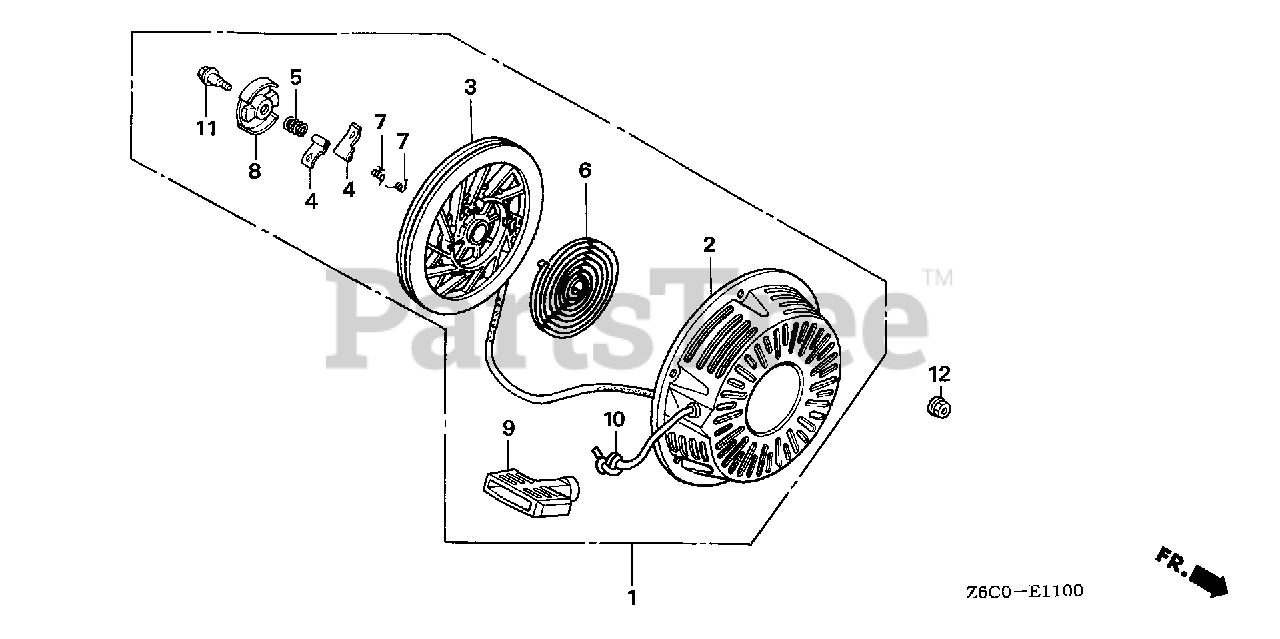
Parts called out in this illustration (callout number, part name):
1	STARTER ASSY., RECOIL *NH1* (BLACK)
1	STARTER ASSY., RECOIL *R280* (POWER RED)
2	CASE, RECOIL STARTER *NH1* (BLACK)
2	CASE, RECOIL STARTER *R280* (POWER RED)
3	PULLEY, RECOIL STARTER
4	RATCHET, STARTER
5	SPRING, FRICTION
6	SPRING, STARTER RETURN
7	SPRING, RATCHET
8	RETAINER, SPRING
9	GRIP, STARTER
10	ROPE, RECOIL STARTER
11	SCREW, CENTER
12	NUT, FLANGE (6MM)
